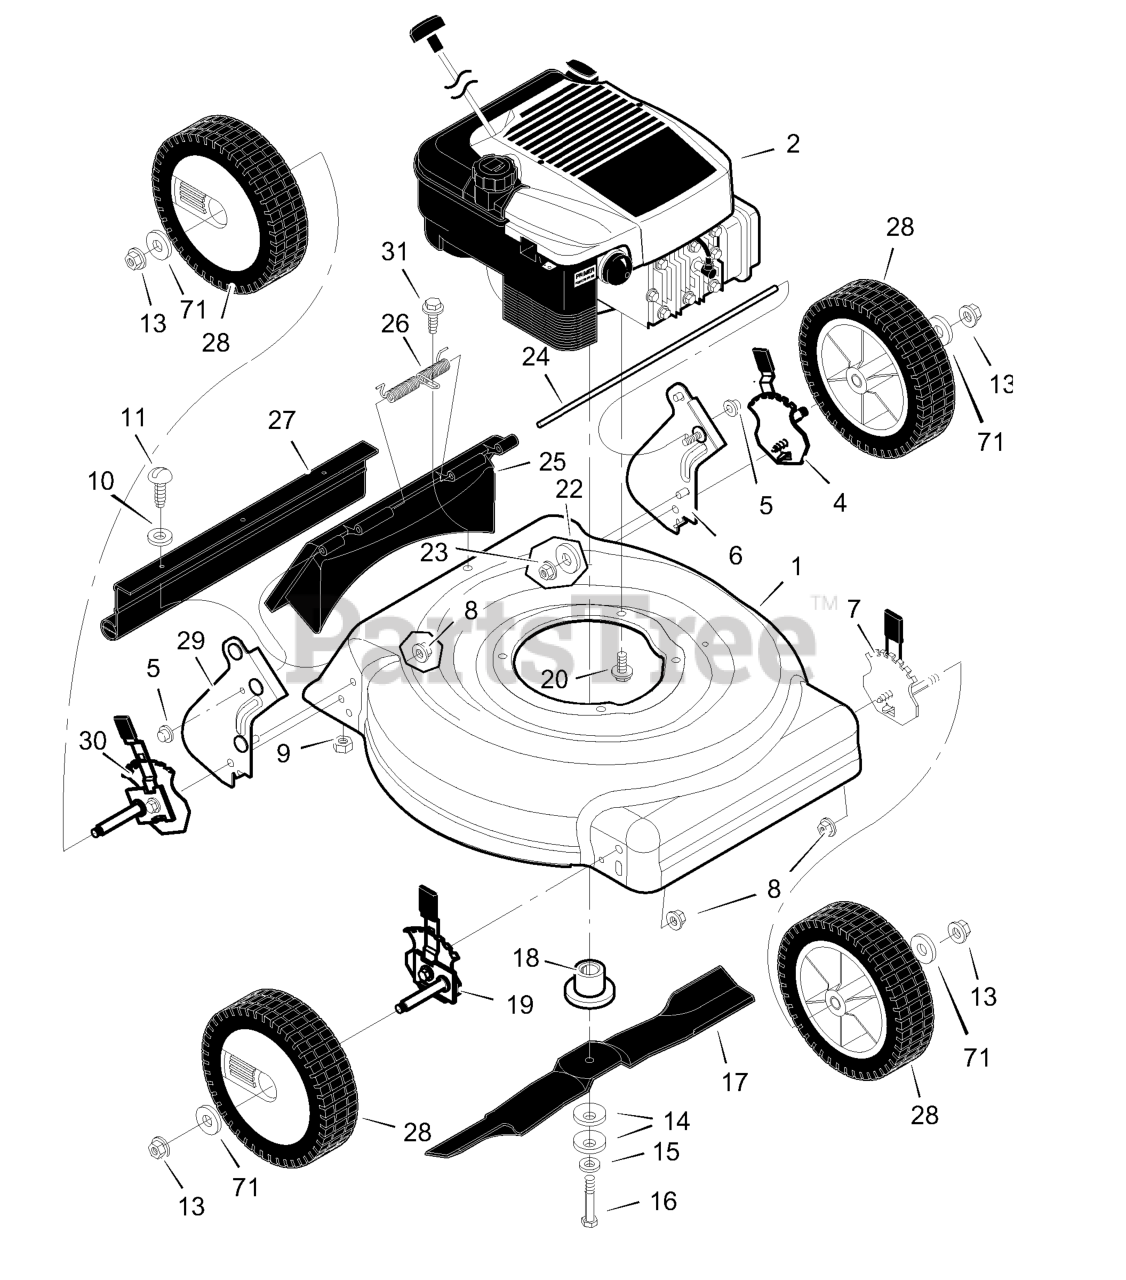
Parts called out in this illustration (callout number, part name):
1	Housing
2	Engine *
4	Adjuster, Left Rear Height
5	Nut, Push
6	Bracket, Left Handle
7	Adjuster, Left Front Height
8	Nut, Flange
9	Nut, Hex
13	Nut, Flange
14	Washer, Belleville
18	Adapter, Blade
19	Adjuster, Right Front Height
20	Bolt, Engine
22	Washer
23	Nut, Flange
24	Rod, Pivot
25	Door, Rear (Black)
27	Guard, Rear
28	Wheel & Tire
29	Bracket, Right Handle
30	Adjuster, Right Rear Height
